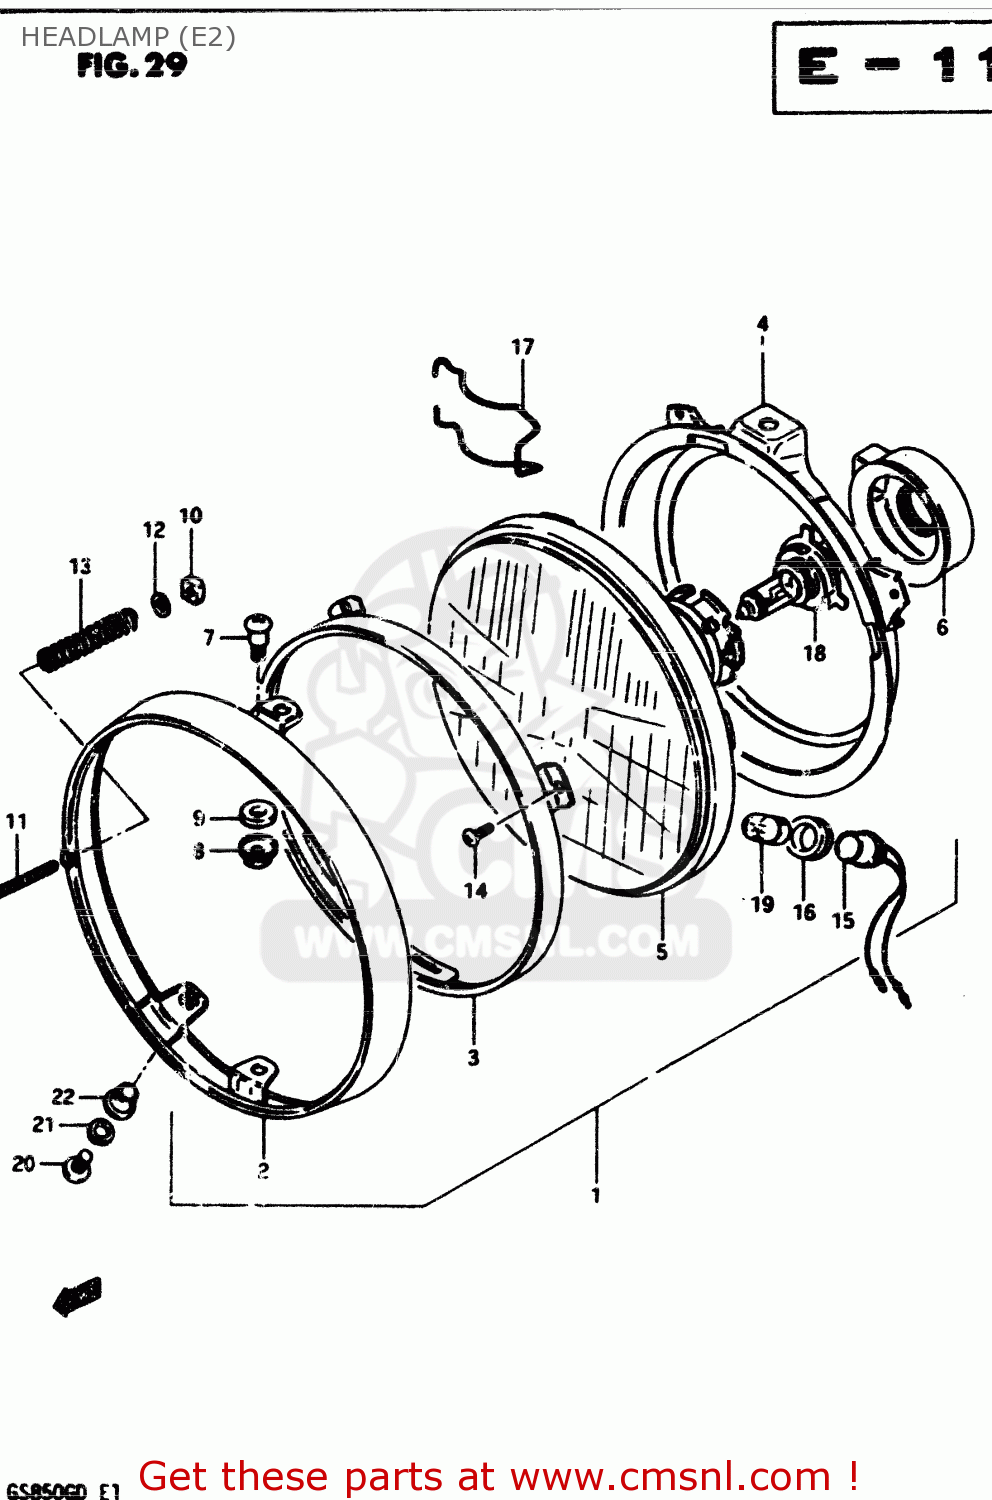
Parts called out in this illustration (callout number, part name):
1	HEADLAMP ASSY
2	RIM
3	RETAINER
4	RING,HEADLAMP UNIT
5	UNIT
6	COVER,HEADLAMP SOCKET
7	SCREW
8	NUT,ADJUSTING
9	SPACER
10	NUT
11	SCREW
12	WASHER
13	SPRING,HEADLAMP ADJUST
14	SCREW
15	SOCKET
16	JOINT,RUBBER
17	CLAMP,HEADLAMP SOCKET
18	BULB(12V60/55W,H4)
19	BULB(12V4W)
20	SCREW
21	WASHER,LOCK
22	WASHER
